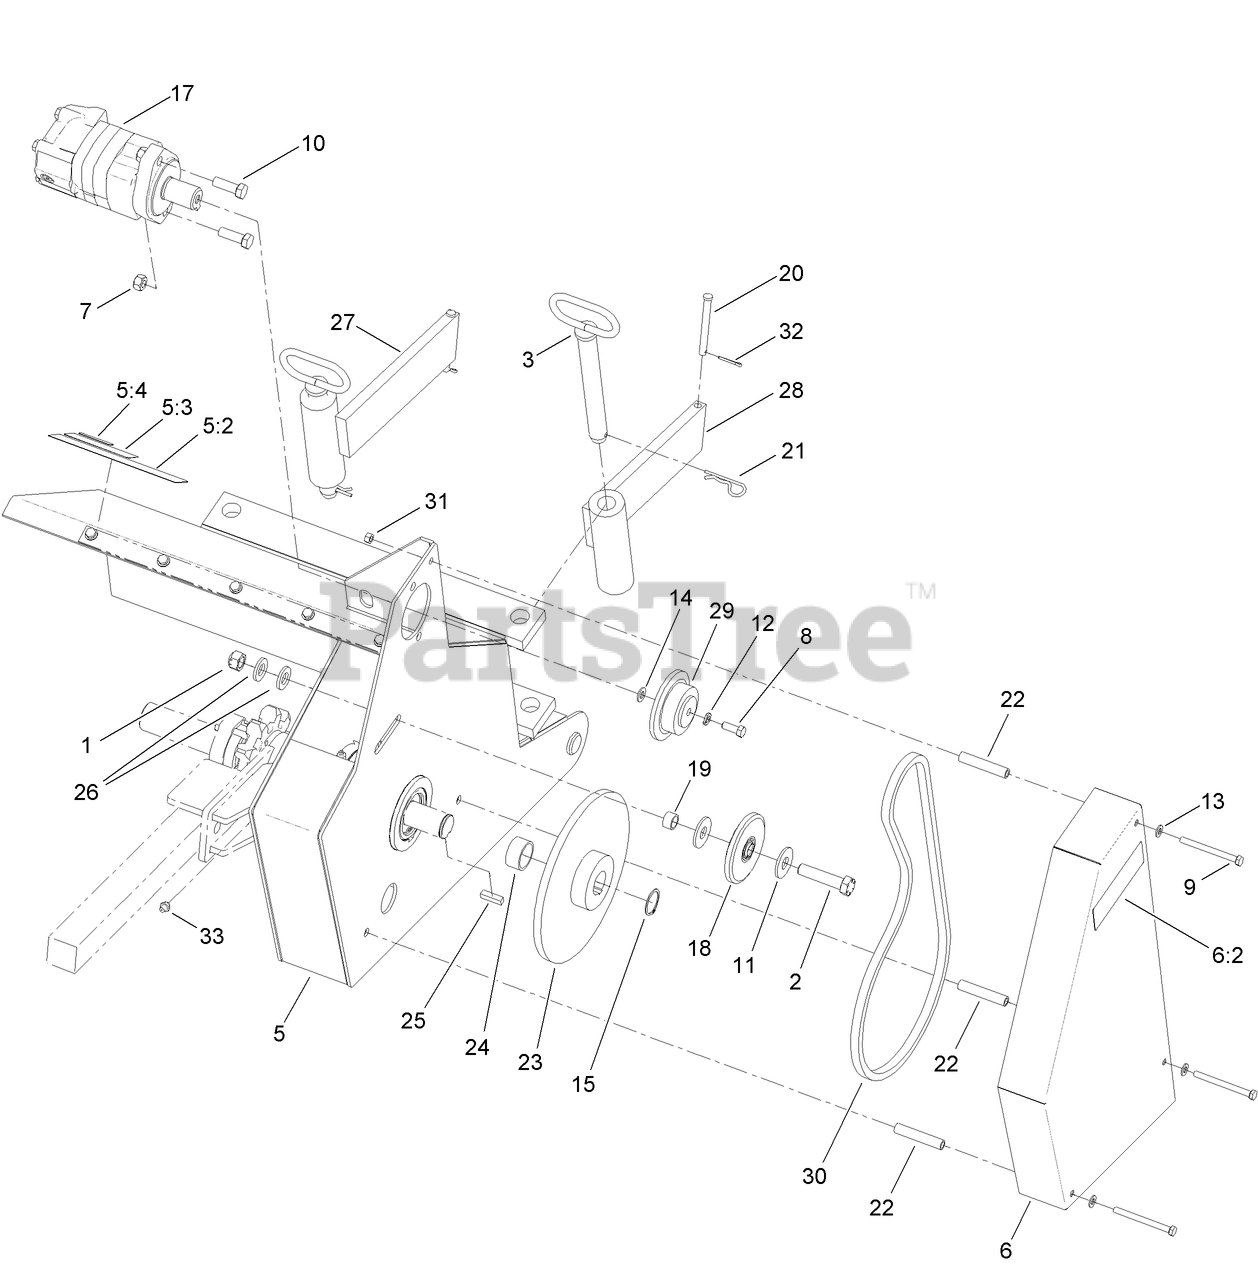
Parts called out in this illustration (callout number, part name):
1	NUT-CROWNLOCK
2	SCREW-HH
3	PIN-MOUNTING
5	FRAME ASM
5:2	DECAL-DANGER, ENTANGLEMENT
5:3	DECAL-DANGER
5:4	DECAL-GREASE
6	COVER ASM
6:2	DECAL-WARNING, CHAIN
7	NUT-LOCK, HEX
8	SCREW-HH
10	SCREW-HH
11	WASHER-FLAT
12	WASHER-LOCK
13	WASHER-PLAIN
14	WASHER-FLAT
15	RING-SNAP, EXTERNAL
17	HYD MOTOR ASM
18	IDLER BEARING AND SPROCKET ASM
19	SPACER-SPROCKET, IDLER
20	PIN-CLEVIS
21	PIN-Hair
23	SPROCKET-HEADSHAFT
26	WASHER-FLAT
27	ARM-MOUNTING, RH
28	ARM-MOUNTING, LH
29	SPROCKET-DRIVE
30	CHAIN-68P
31	NUT-LOCK, CONE
32	PIN-COTTER
33	FITTING-GREASE
